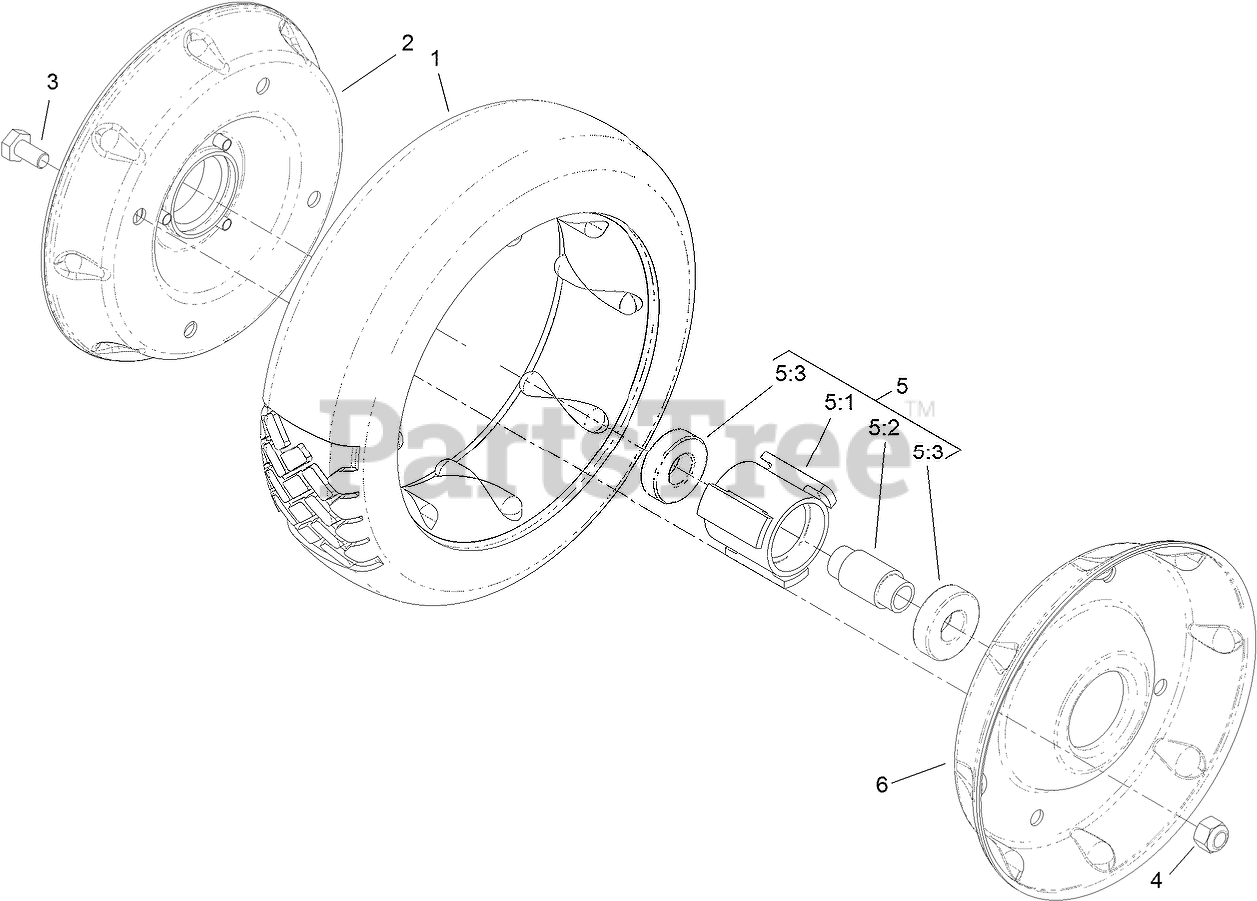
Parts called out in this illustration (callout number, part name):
2	WHEEL HALF AND GEAR ASM
3	SCREW-HH
4	NUT-LOCK, NI
5	HUB AND BEARING ASM
5:1	HUB-BEARING
5:2	SPACER-BEARING
5:3	BEARING-BALL
6	RIM-HALF, WHEEL
